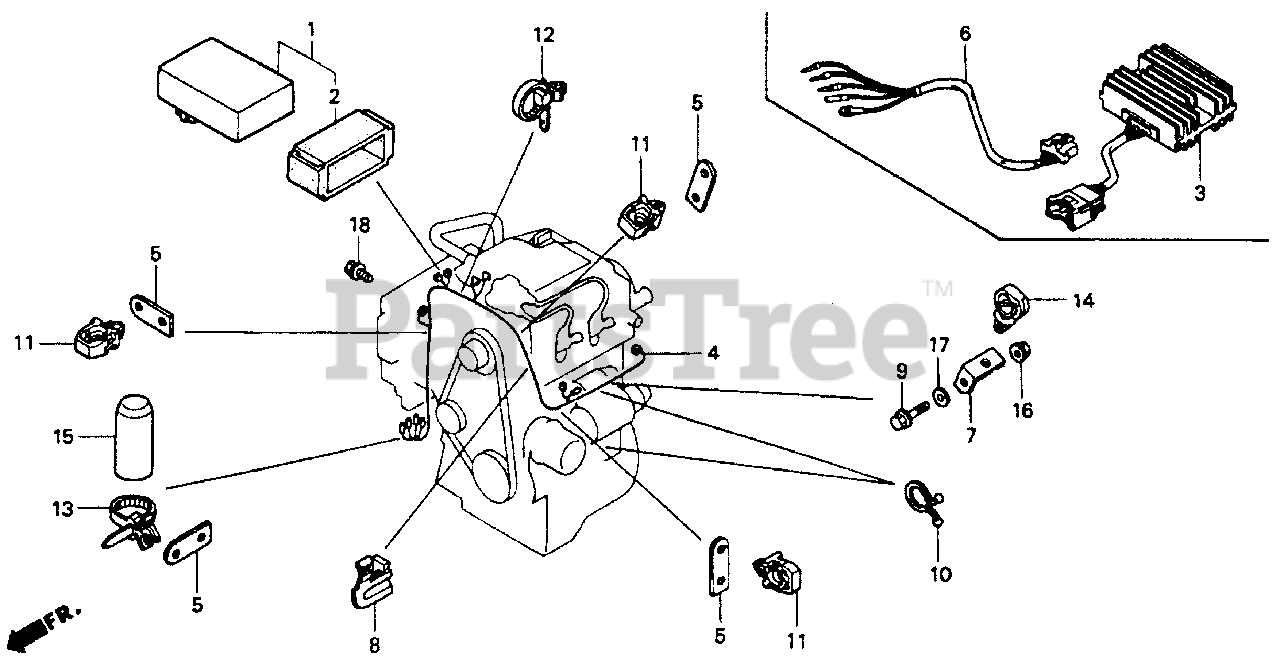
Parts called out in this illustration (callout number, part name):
1	MODULE, IGNITION CONTROL (CDI)
2	CUSHION, IGNITION CONTROL (Honda Code 2796621). MODULE
3	RECTIFIER ASSY., REGULATOR (Honda Code 4210225). (20A)
3	RECTIFIER ASSY., REGULATOR (Honda Code 7664725). (20A)
4	HARNESS ASSY., ENGINE
5	BRACKET, WIRE HARNESS CLIP
6	SUB-WIRE HARNESS ASSY.
7	BRACKET, WIRE HARNESS CLIP (H)
8	STAY, SCHRAEDER VALVE (Honda Code 3974888). CONNECTOR
9	BOLT, FLANGE (5X25)
10	CLIP, PURSE LOCK
11	CLIP, WIRE HARNESS (10MM)
12	STRAP, CABLE (105MM) *NH1* (Honda Code 1685536). (BLACK)
13	BAND, WIRE HARNESS (150MM) (Honda Code 1352103). (BLUE)
14	CLIP, WIRE HARNESS (25MM)
15	TUBE, CORD (25MM)
16	NUT, FLANGE (5MM)
17	WASHER, PLAIN (5MM)
18	BOLT, FLANGE (6X12)
